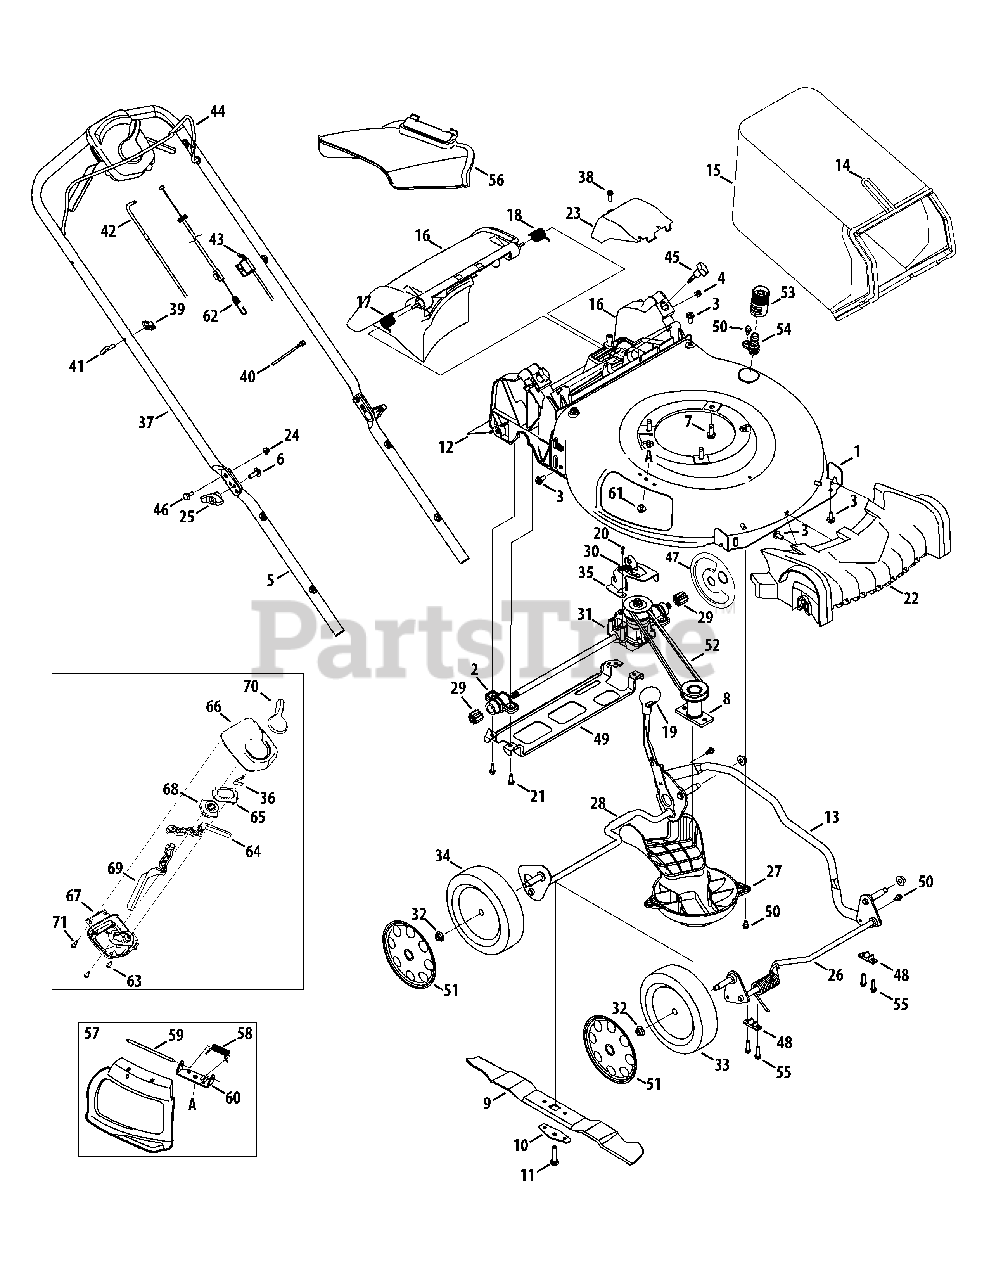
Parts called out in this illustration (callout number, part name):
1	Deck , 21"
2	Bearing Assembly
3	Screw, 5/16-14 x .750
4	Nut, Sq., 1/4-20
5	Lower Handle
6	Carriage Screw ,5/16-18
7	Screw, 3/8-16 x 1.00
8	Blade Adapter
9	Mulching Blade
10	Blade Bell Support
11	Screw, 3/8-24 x 1.50
12	Trailing Shield
13	Cross Bracket
14	Grass Catcher Frame
16	Rear Discharge Door Assembly
17	Torsion Spring - RH
18	Torsion Spring - LH
19	Adjustment Lever Knob
20	Screw, Hex Washer, .159 x .43
21	Screw, 1/4-15 x 1.25
22	Front Cover
23	Transmission Cover
24	Nut, Flange Lock, 1/4-20
26	Front Axle Assembly
27	Engine Baffle
28	Rear Axle Assembly
29	Spur Gear, 10T
30	Exten. Spring, 2.405
31	Transmission Assembly
32	Flange Lock Nut, 3/8-16
33	Rear Wheel
34	Front Wheel
35	Transmission Bracket
38	Screw, 1/4-15 x .750
40	Cable Tie
41	Rope Guide
42	Speed Adjustment Cable
43	Control Cable
45	Wing Nut
46	Sldr. Screw, .375 x .126 x 1/4-20
47	Wheel Dust Cover
48	Bushing, Lock, .505 Dia. X .62
49	Rear Support Bracket
50	Screw, Shldr., 1/4-20 x .50
51	Hubcap, 8"
53	Water Nozzle Adapter
54	Water Nozzle
55	Screw, 1/4-15 x 1.000
56	Side Discharge Chute
57	Mulch Plug (Incl. 58-60)
58	Torsion Spring
60	Chute Deflector Bracket
61	Screw, 1/4-20 x .500
62	Drive Cable
63	Screw, 1/4-15 x .750
64	Control Lever LH
65	Cable Adjust Plate
66	Upper Housing
67	Lower Housing
68	Speed Adjust Actuator
69	Control Lever RH
70	Speed Select Lever
71	Screw., Shldr, 1/4-15 x .970
